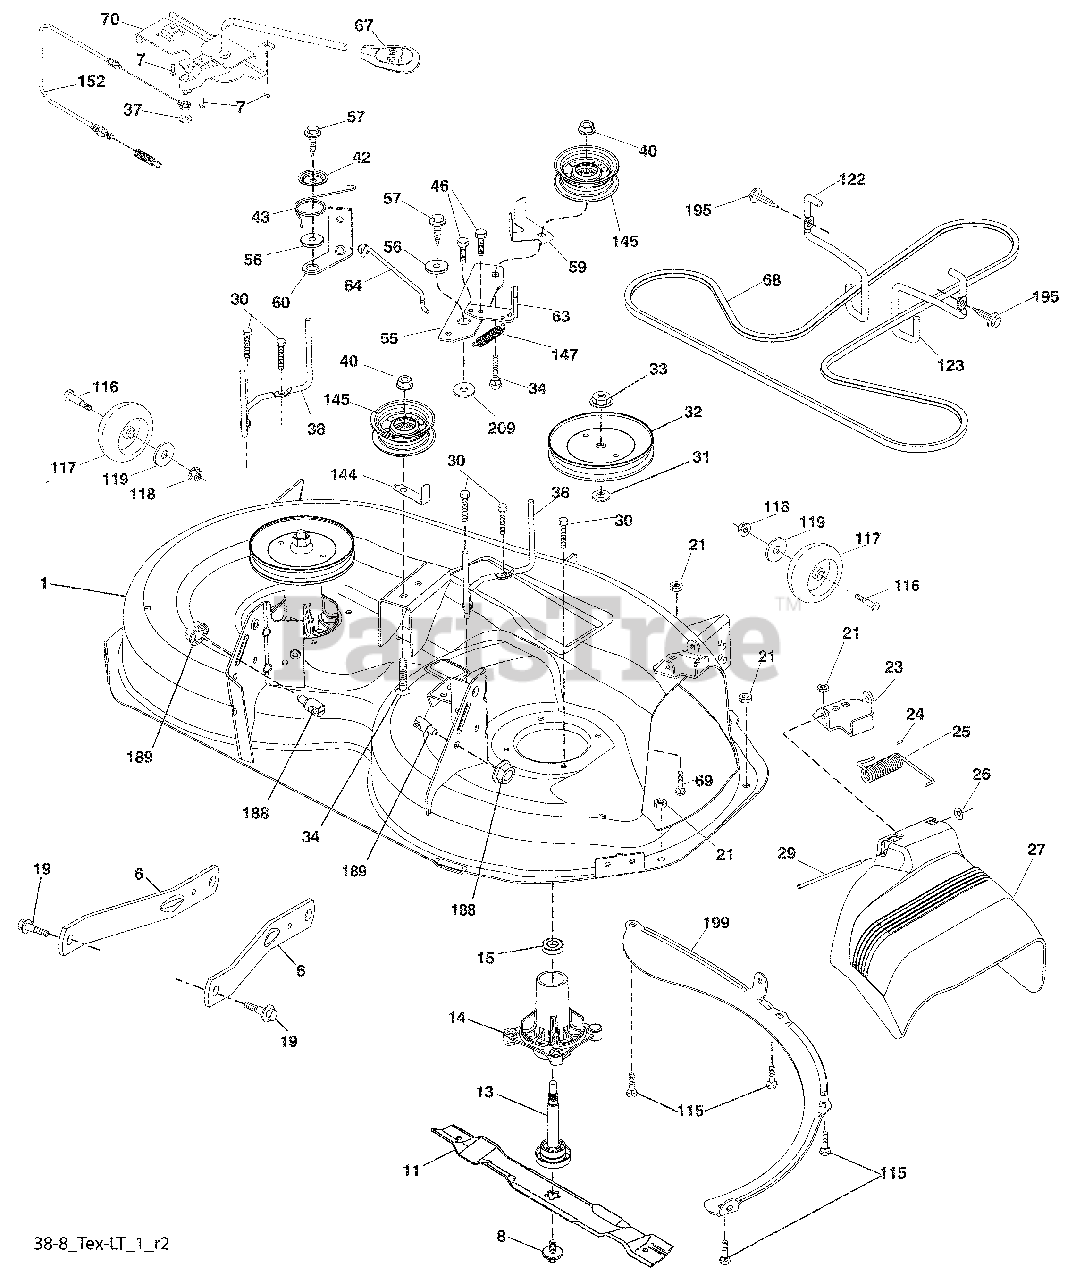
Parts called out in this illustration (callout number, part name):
1	Mower Housing
6	Arm Suspension
7	Screw #10 x 0.750 BOS Thread
8	Bolt/Washer asm 7/16-20 unf
11	Blade Mulching
13	Shaft Assembly, Mandrel
14	Housing, Mandrel
15	Bearing, Ball, Mandrel
19	Bolt, Shoulder
21	Nut, Crownlock 5/16-18 unc
23	Bracket, Deflector
24	Cap, Sleeve
25	Spring, Torsion, Deflector
27	Shield, Deflector
29	Rod, Hinge
30	Screw Thdrol Rolling Wsh Hd
31	Washer, Spacer
32	Pulley, Mandrel
33	Nut, Toplock, Flanged
34	Bolt Carr Sh. 3/8-16 x 1-1/2 Gr. 5
37	Washer
38	Keeper Belt LH Mandrel
40	Nut, Lock Flg. 3/8-16 unc
42	Spring Torsion Brake
43	Spring Torsion Retainer
46	Screw 1/4-20 x 5/8
55	Arm, Idler
56	Spacer, Retainer
57	Screw 3/8-16 x 1
59	Guard, Tuv Idler
60	Arm Brake Mower LH
63	Arm Brake Mower RH
64	Link Brake
67	Handle Clutch Cable
69	Bolt
70	Clutch Asm Manual
115	Bolt Carr. 5/16-18 x 5/8
116	Bolt, Shoulder
117	Wheel, Gauge
118	Nut Lock 3/8-16 UNC
119	Washer 3/8 x 7/8 x 14 Ga.
122	Keeper Belt Engine LH
123	Keeper Belt Engine RH
144	Keeper Belt
145	Pulley Idler
147	Spring Return
152	Manual Clutch Cable
188	Stud Fastener
189	Nut Lock Hex Flange
195	Screw 3/8-16 x 3/4
199	Baffle Vortex
209	Washer 13/32 x 2 x 10
